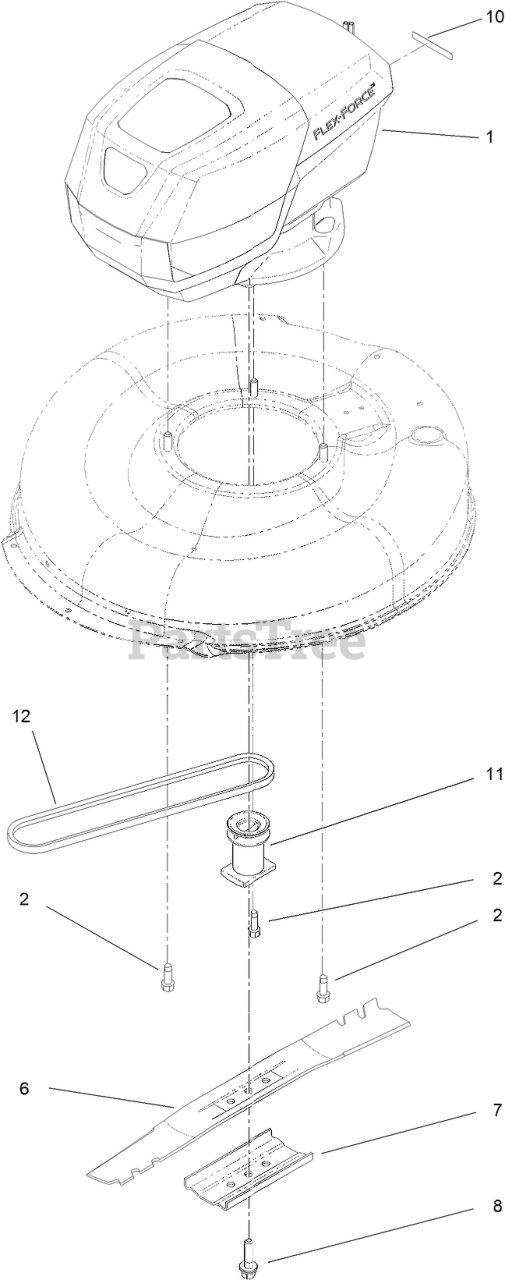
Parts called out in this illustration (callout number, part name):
1	MODULE-MOTOR
2	SCREW-TAPTITE
6	BLADE-21IN (MULCH, HS)
7	SUPPORT-BLADE
8	BOLT-BLADE
10	DECAL-WARNING
11	DRIVER-BLADE
12	V-BELT
